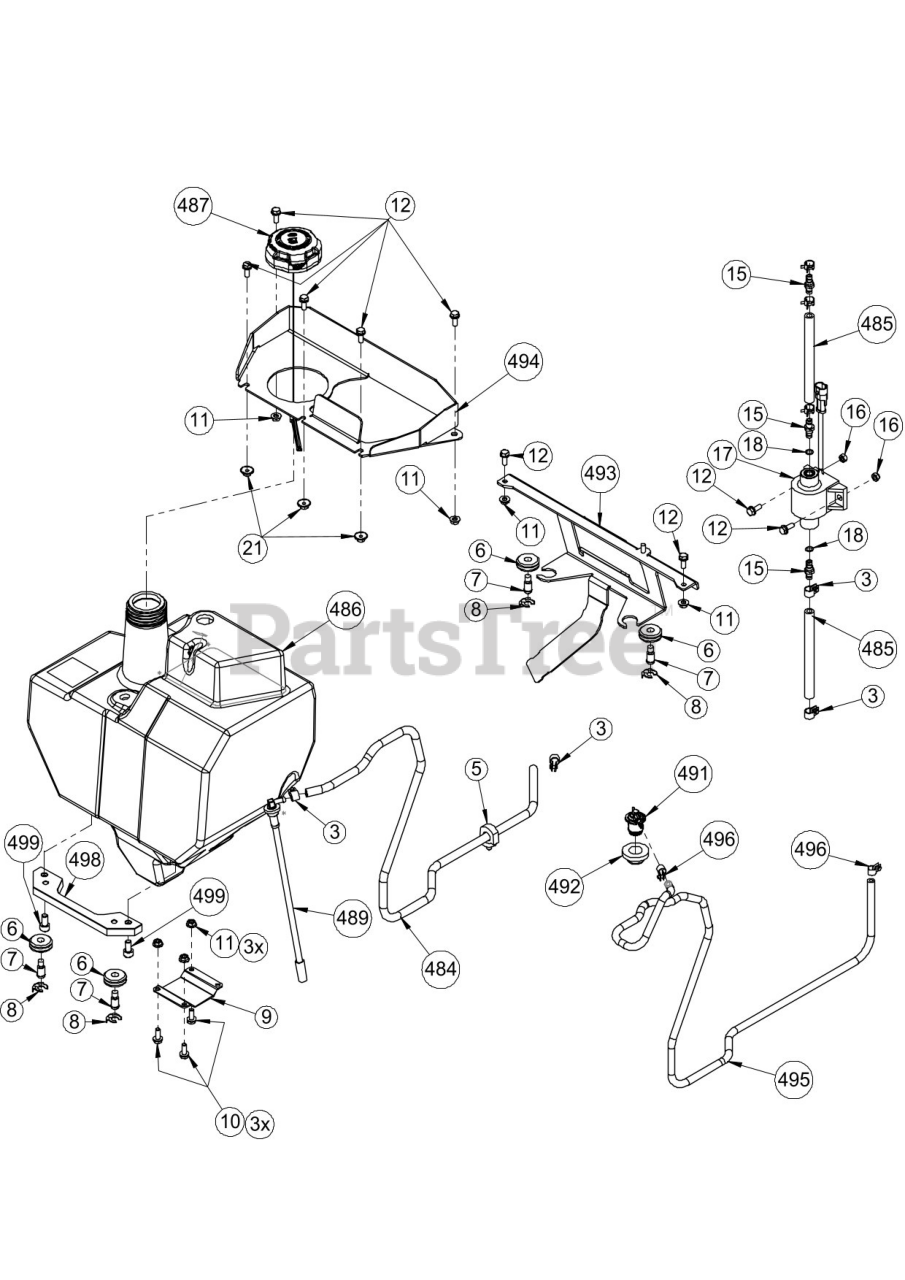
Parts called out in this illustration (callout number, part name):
3	CLAMP, HOSE 13/9
5	RETAINER, FUEL HOSE
6	GROMMET, RUBBER
7	BOLT, TANK
8	CLIP, TANK
9	GUARD, TANK MUD
10	TORX PHCS SELF TAP M6X12 8.8 ZCC
11	NUT, FLG SLF LK M6 CL 8 ZCC
12	NUT, FLG SLF LK M6X16
15	FITTING, FUEL LINE
16	NUT, LK V-M6 DIN 980 8 ZCC
17	PUMP, FUEL
18	O - RING 8X1,5
21	NUT, HEX SEMS M6
484	1 INCH OF HOSE, .25 LOW-PERM BULK GAS
485	1 INCH OF HOSE, .25 LOW-PERM BULK GAS
486	ASM, TANK FUEL - OVIS
487	CAP-FUEL- 2.25 RATCHET INLET V
489	PICKUP, FUEL
491	VALVE, COMBINATION VENT 3/16
492	GROMMET, REMOTE VENT NITRILE
493	BRACKET, TANK MOUNTING
494	Plate, Tank
495	HOSE, .188 30R7 BULK
496	CLAMP, HOSE 11/9
498	BRKT, TANK MOUNTING
499	SCR-SKH M8-1.25X16
